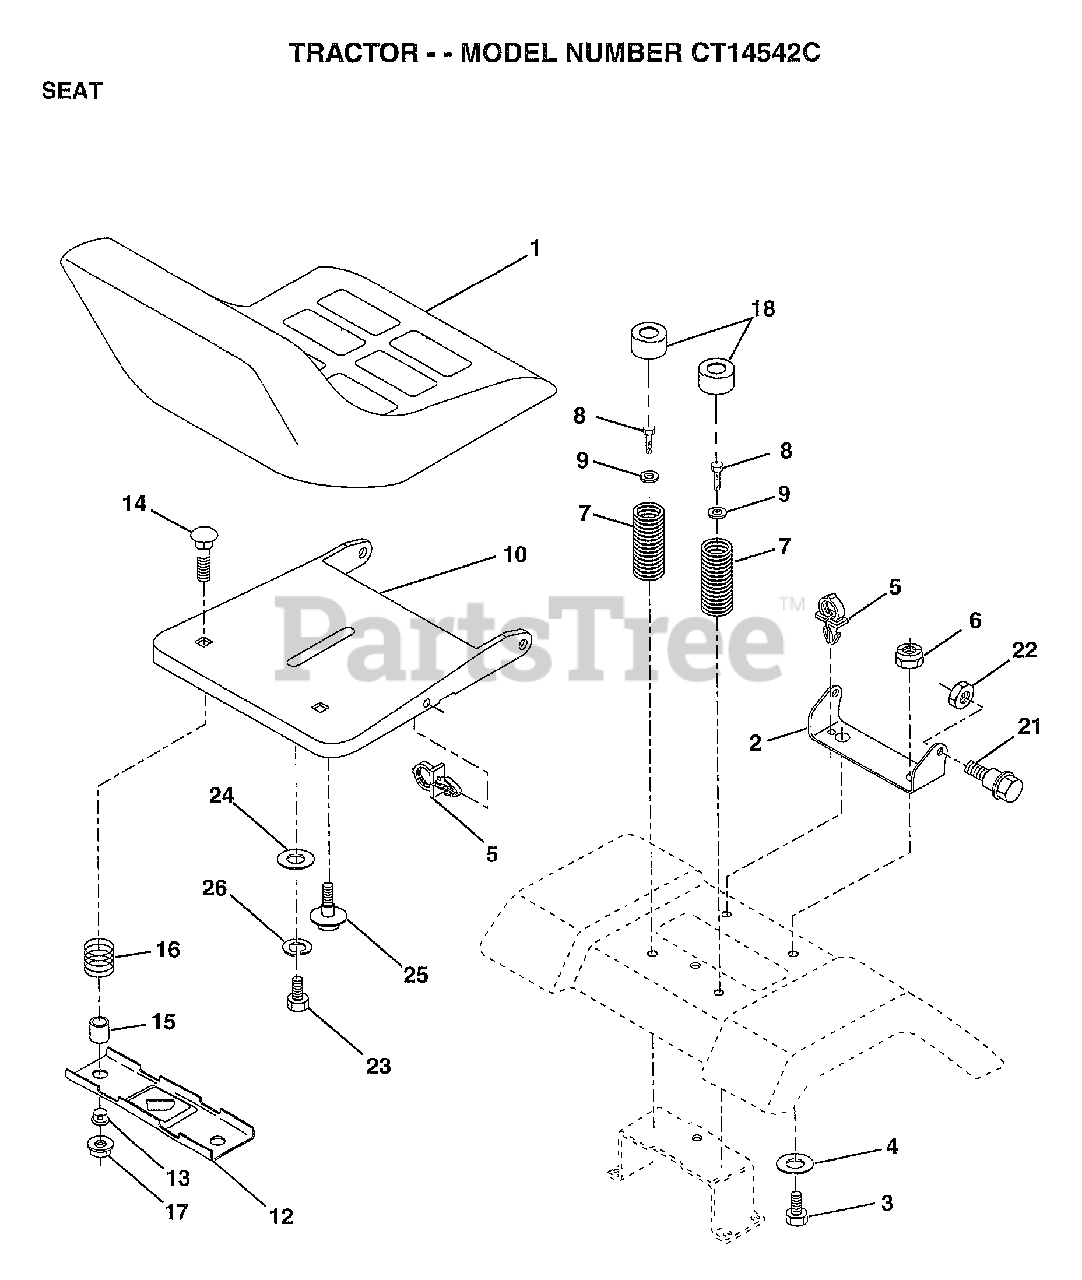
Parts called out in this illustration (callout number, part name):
2	BRACKET PVT SEAT
3	BOLT
4	WASHER PM
5	CLIP.PUSH-IN.HING
6	NUT
7	SPRING COMPRESSIO
8	SCREW GTV
9	WASHER
10	PAN-SEAT
11	"KNOB 1/2"" YT"
12	BRKT SWITCH
13	BUSHING
15	SPACER SPLIT
16	SPRING COMPRESSED
21	"BOLT,SHOULDER"
24	WASHER
25	"BOLT,SHOULDER"
